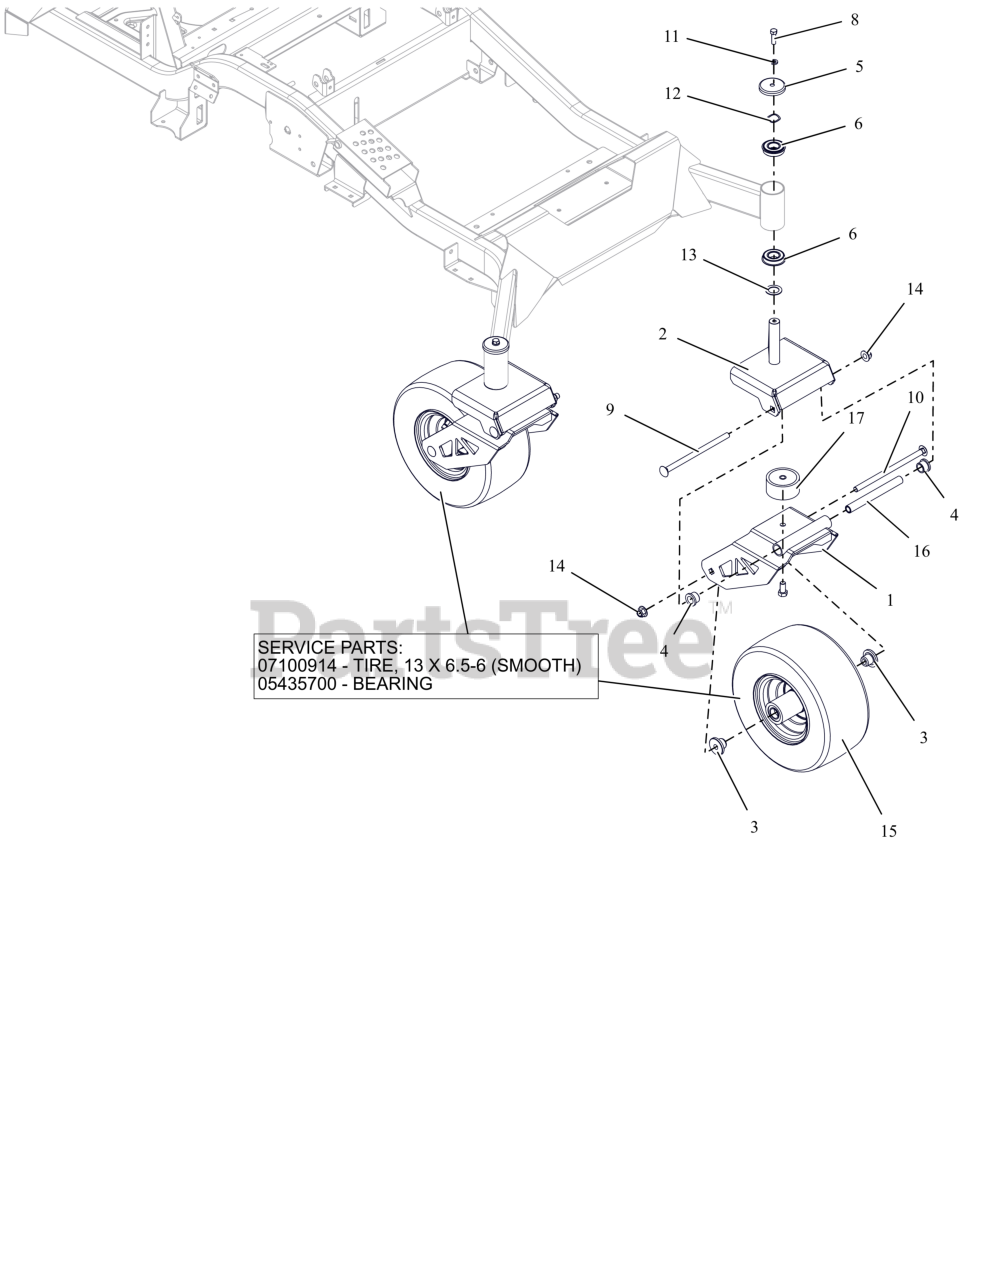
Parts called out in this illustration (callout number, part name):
1	WLDMT- LOWER SUSPENSION (ORG)
2	WLDMT- UPPER SUSPENSION FORK
3	SPACER, FRONT WHEEL
4	BUSHING, FLANGE .75X.75X1.0
5	SHIELD, AXLE BEARING
6	BEARING, BALL -2.000 OD X 1.000 ID X .5625 W/RING
7	BLT, HEX .50-13X1.00 G5 ZCC
8	BLT, HEX .38-16X1.25 G5 ZCC
9	BLT, RHSN .50-13X8.50 G5 ZCC
10	BLT-RHSN .50-13X9.00 G5 ZCC NS
11	WSHR, LK-HVY .375X.115 ZCC
12	WSHR-WAVE 1.0X1.25X.028 .145FH
13	WSHR-HRD-THRS 1.007X1.542X.062
14	NUT,NYL-FLG .50-13 GF ZCC
15	ASM, WHL/TIRE 13X6.50-6
15	LAWN TIRE FRONT, 13X6.50-6 SMOOTH
15	BRG, 25MM ID X 52MM OD X 15MM
15	VALVE STEM ASS'Y
15	TIRE TUBE, 13/6.5-6 4 PLY TR87 90 BENT VALVE
16	ROD- FORK PIVOT
17	SPCR- RUBBER SUSPENSION
